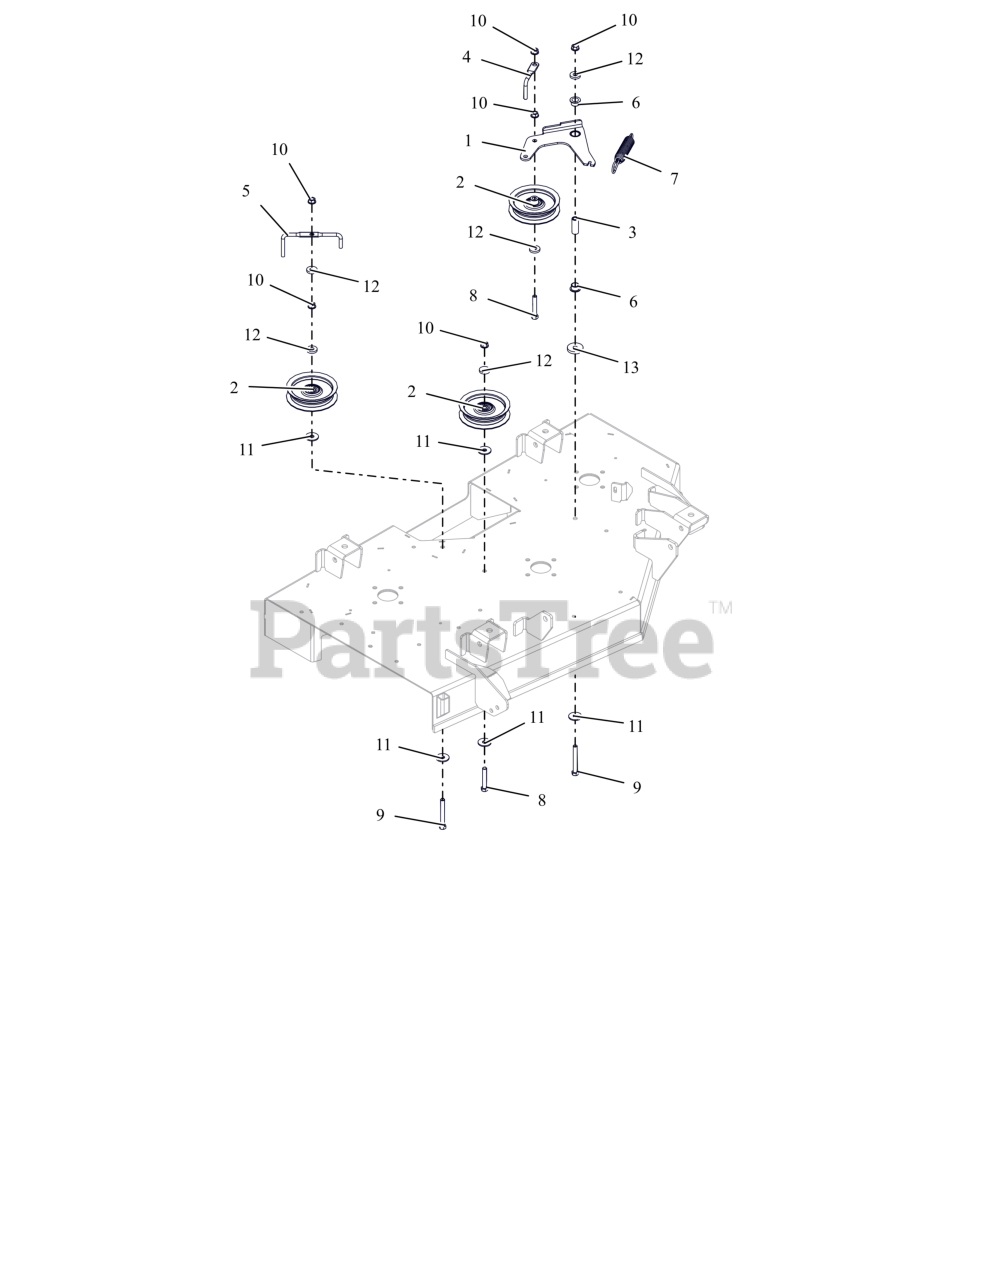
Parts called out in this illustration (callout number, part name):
1	WLDMT, IDLER ARM-42"
2	IDLER, FLAT - 4.06" X .75"
3	SPACER, .375IDX.625ODX1.66 PM
4	WIREFORM-BELT FINGER
5	BELT FINGER
6	BSHG-FLG, .625X.750X.500X1.00
7	SG-TENS .135X.98X6.0 WLD 62
8	BLT,HEX .38-16X2.25 G5 ZCC
9	BLT, HEX .38-16X3.00F G5 ZCC
10	NUT-LK-CTR-FLG .375-16 GF ZCC
11	WSHR FL STL .406X1.25X.10ZC120
12	WSHR, FLT .406X1.00X.188 ZCC
13	WSHR, FLT .406X1.50X.245 ZCC
